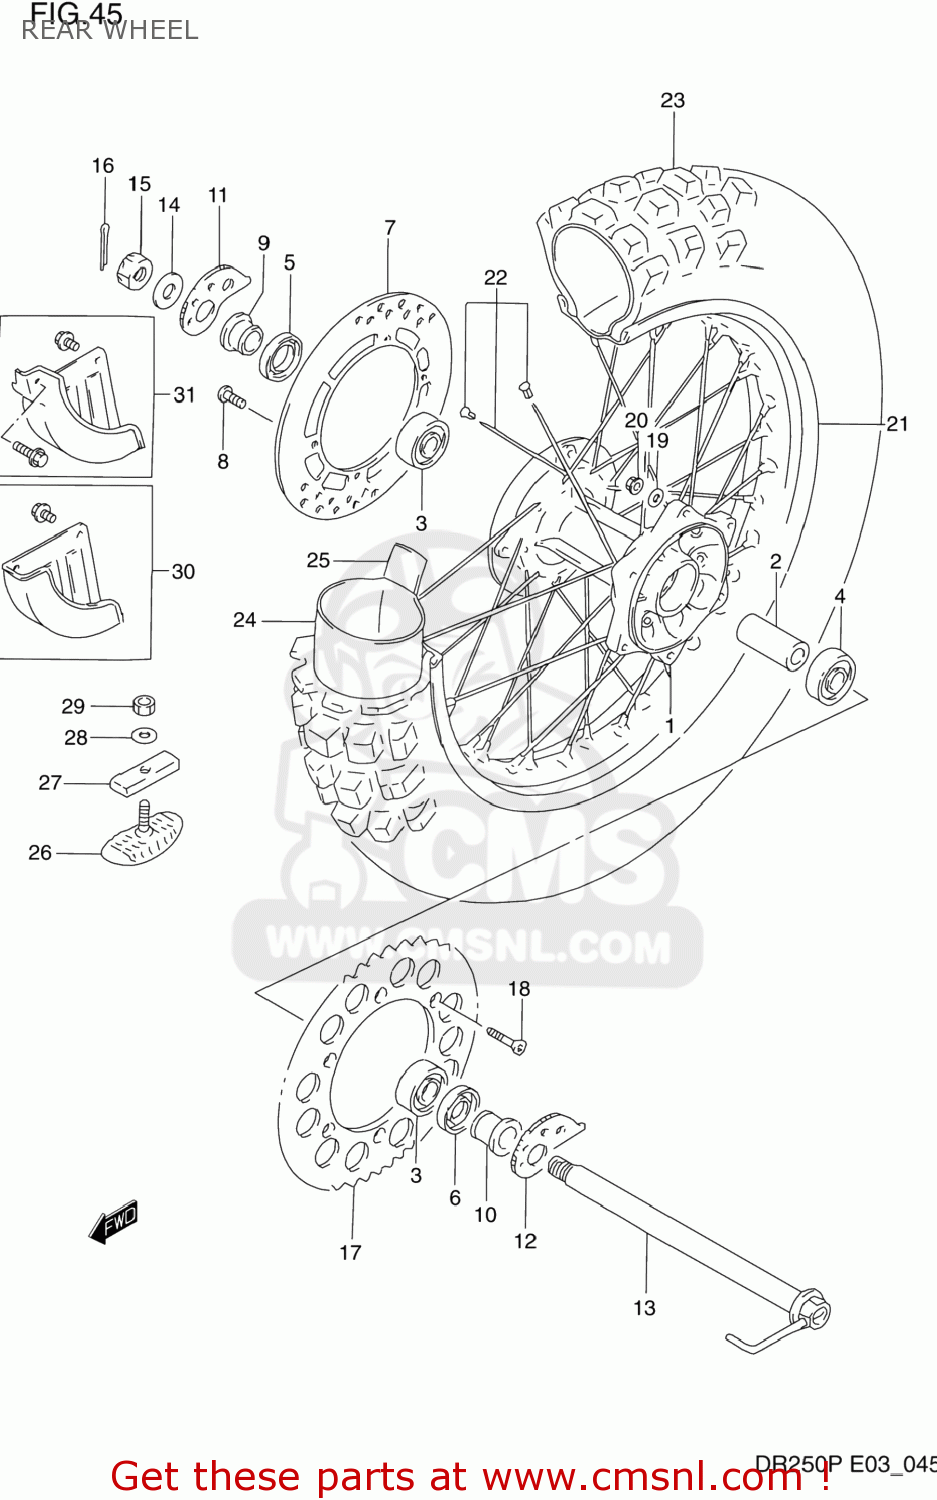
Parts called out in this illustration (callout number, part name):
1	HUB,REAR WHEEL
2	SPACER,RR HUB BEARING
3	BALL BEARING
4	BEARING
5	SEAL,OIL(26X42X8)
6	SEAL,OIL(26X47X5)
7	DISC,RR BRAKE
8	BOLT
9	SPACER,RR AXLE,R
10	SPACER,RR AXLE,L
11	ADJUSTER,CHAIN
12	ADJUSTER,CHAIN,L
13	AXLE,RR
14	WASHER (19X32X3.2)
15	NUT 18MM
16	PIN,COTTER
17	SPROCKET,REAR
18	SCREW(8X33.5)
19	WASHER
20	NUT
21	RIM,RR WHEEL(18X2.15 AL)
22	SPOKE SET,RR WHEEL
23	TIRE COMP,REAR 110/100-1
24	TUBE,INNER
25	PROTECTOR,INNER TUBE
26	STOPPER,BEAD
27	CUSHION,BEAD STOPPER
28	WASHER
29	NUT 8MM
30	COVER SET,REAR BRAKE DRUM
31	COVER SET,RR BRAKE DISC
